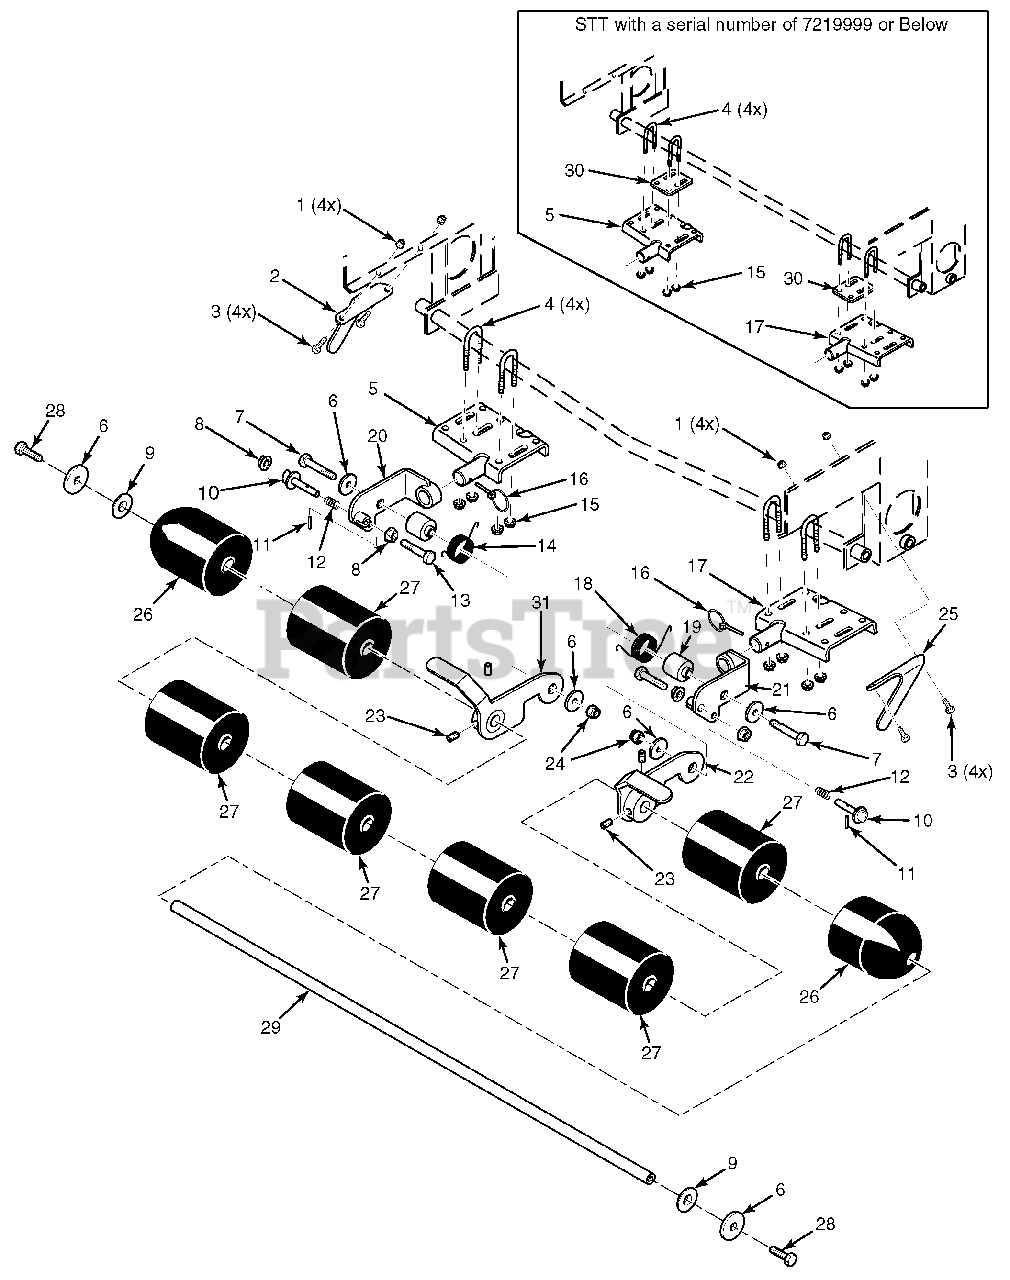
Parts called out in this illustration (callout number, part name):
1	Nut, Elastic Stop 3/8-16
2	Striper Stop, L.H. - STT Only
3	Bolt, Hex Head 3/8-16 x 1"
4	U-Bolt, 5/16-18 x 1"
5	Mounting Bracket Weldment, LH.
6	Flatwasher, 3/8-.406 x 1-1/2" 7 Gauge
7	Bolt, Hex Head 3/8-16 x 2-3/4"
8	Nut, Serrated Flange 3/8-16
9	Flatwasher, 3/4-.812 x 1-3/8 x .100
10	Pin, Lift Latch
11	Pin, Slotted Spring .156 x 3/4"
12	Spring, Lock Pin
13	Bolt, Hex Head 3/8-16 x 2-1/2"
14	Spring, Torsion L.H.
15	Nut, Serrated Flange 5/16-18
16	Quick Pin, .188 Dia.
17	Mounting Bracket Weldment, R.H.
18	Spring, Torsion R.H.
19	Hub, Striper
20	Pivot Weldment, L.H.
21	Pivot Weldment, R.H.
22	Hinge Weldment, R.H.
23	Set Screw, 3/8-16 x 1/2"
24	Nut, Elastic Stop 3/8-16
25	Striper Stop, R.H. - STT Only
26	Wheel, Striper End
27	Wheel, Striper
28	Bolt, Hex Head 3/8-16 x 1" (Special Lock)
29	Roller Shaft
30	Spacer, Striper Mounting
31	Hinge Weldment, L.H.
